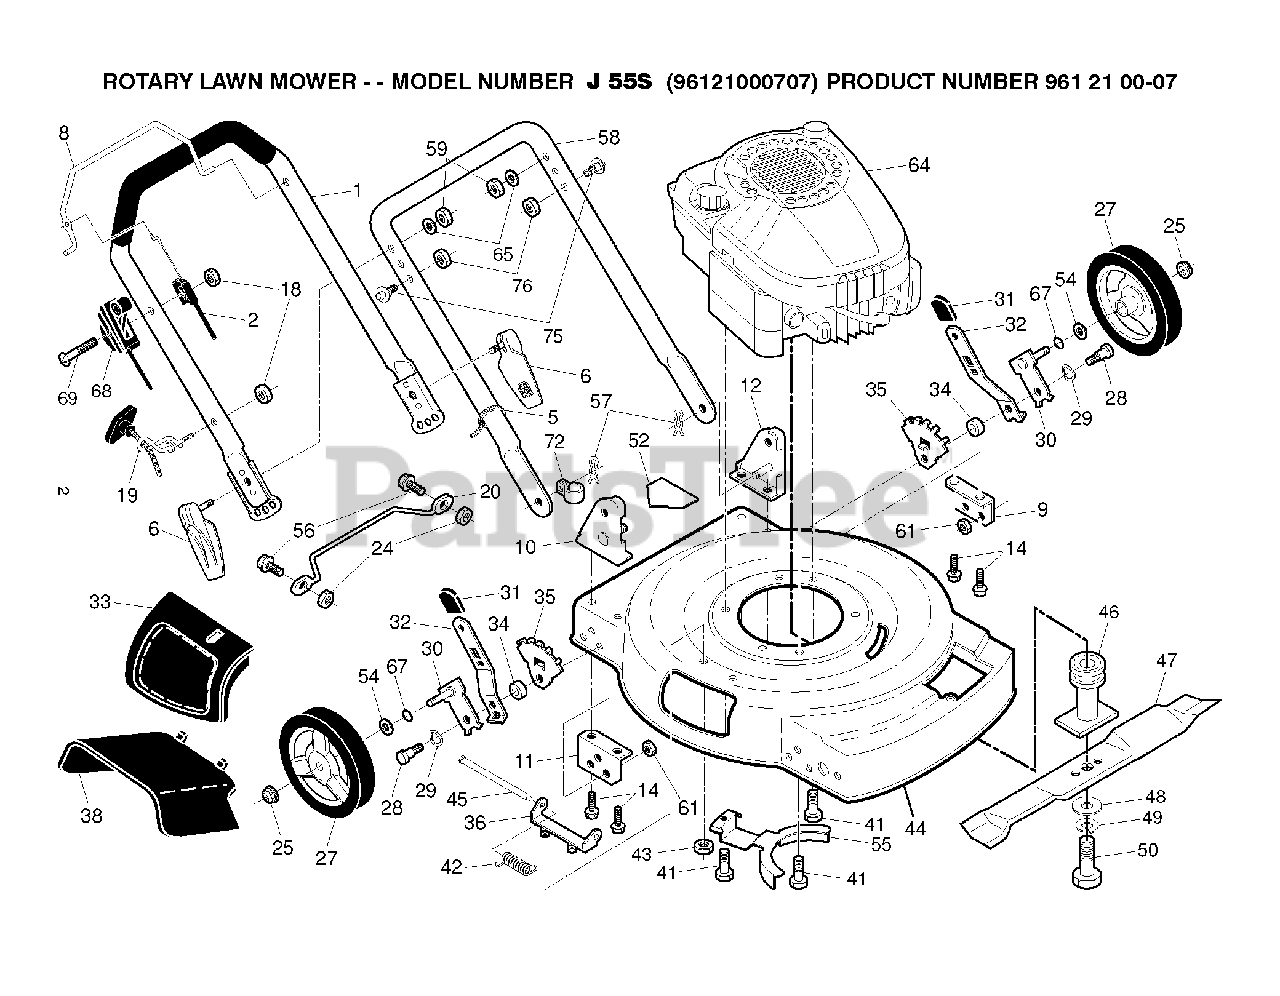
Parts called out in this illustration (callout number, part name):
2	ENGINE ZONE CONTROL CABLE
5	TIE GUIDE
14	SCREW 5/16-18
18	NUT
19	GUIDE.ROPE.STD.BLK.ZIN
25	NUT.HEX.FLANGE.3/8-16.LOCKNUT
27	WHEEL & TIRES ASSY, FRONT
28	BOLT SHOULDER 3/8 -16X1
29	WASHER FLAT
30	AXLE ARM ASSY.
31	SELECTOR KNOB
32	SPRING.SEL.EXT.21.DOMED.12/14
34	SPACER.HEIGHT.ADJUSTER
35	BRACKET.ADJ.WHEEL.5POS.ADS
36	HINGE BRACKET
41	BOLT 3/8-16X1-1/8
42	TORSION SPRING
43	LOCKNUT
45	ROD.HINGE.COMBI-C
46	ADAPTER.BLADE/PULLEY.25M
48	WASHER,HARDEN
49	LOCKWASHER
50	SCREW, HEX HD 3/8-24 X 1-3/8
52	DECAL.INTERNATIONL.CUTFINGER
54	WASHER PM
55	BRACKET.ENG/BELTKEEPER.BZP
57	HAIRPIN COTTER
61	LOCKNUT
65	WASHER.20X8.5
67	O-RING..070X.487.NEOPRENE
72	CLIP.CABLE.BLK
75	STUD.QUICK.ADJUST
76	NUT, LOCK 5/16-18
